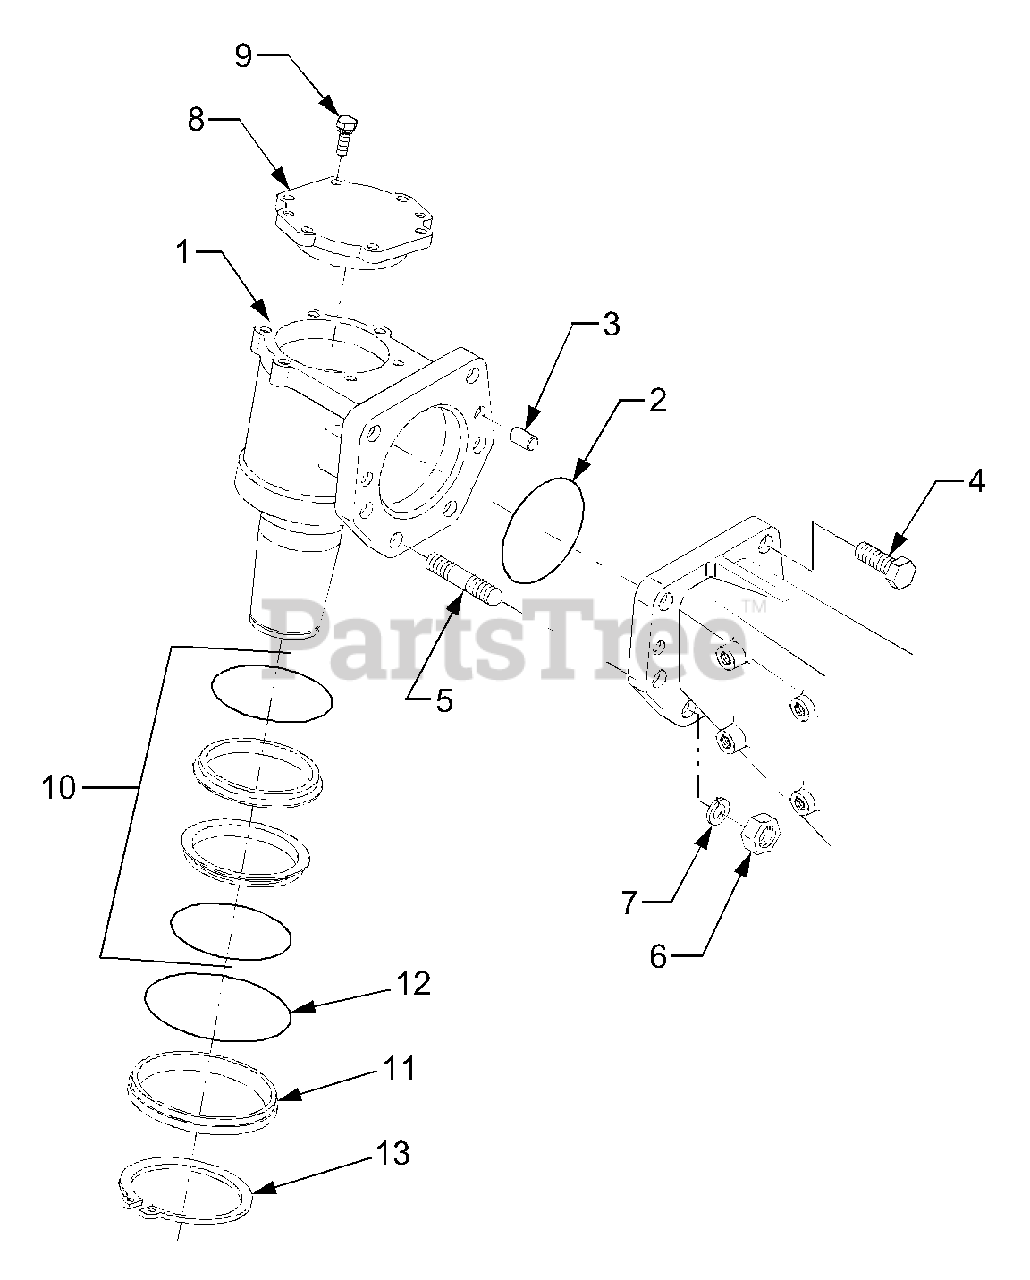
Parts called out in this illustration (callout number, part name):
1	Case, Bevel Gear
3	Pin, Straight
7	Washer, Spring
8	Cover, Bearing
10	Floating Seal Ass'y
